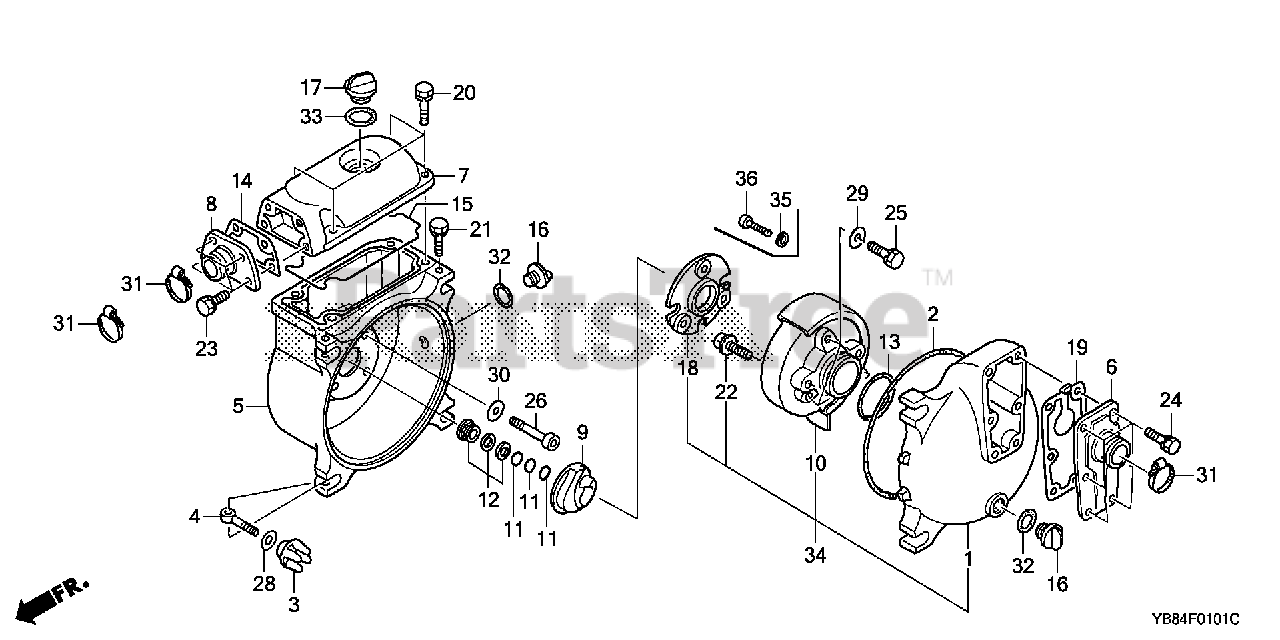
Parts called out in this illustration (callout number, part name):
1	COVER, FR.
2	GASKET, FR. COVER
3	KNOB, FR. COVER
4	BOLT, FR. COVER SETTING
5	CASING
10	CASE, VOLUTE
11	WASHER, SHIM
12	SEAL ASSY., MECHANICAL
14	GASKET, OUTLET
15	GASKET, HEAD
16	CAP, PLUG (32MM)
17	CAP, PLUG (40MM)
18	PLATE, WEAR
19	GASKET, HOSE COUPLING
20	BOLT-WASHER (10X30)
21	BOLT-WASHER (12X45)
23	BOLT-WASHER (10X30)
24	BOLT-WASHER (10X25)
25	BOLT-WASHER (6X16)
26	BOLT, SOCKET (8X55)
28	WASHER, PLAIN
29	WASHER, PLAIN (6MM)
30	WASHER (8MM) (AL.)
32	O-RING (32MM)
33	O-RING (40MM)
35	WASHER, CLUTCH (8MM)
36	BOLT, SOCKET (8X35)
